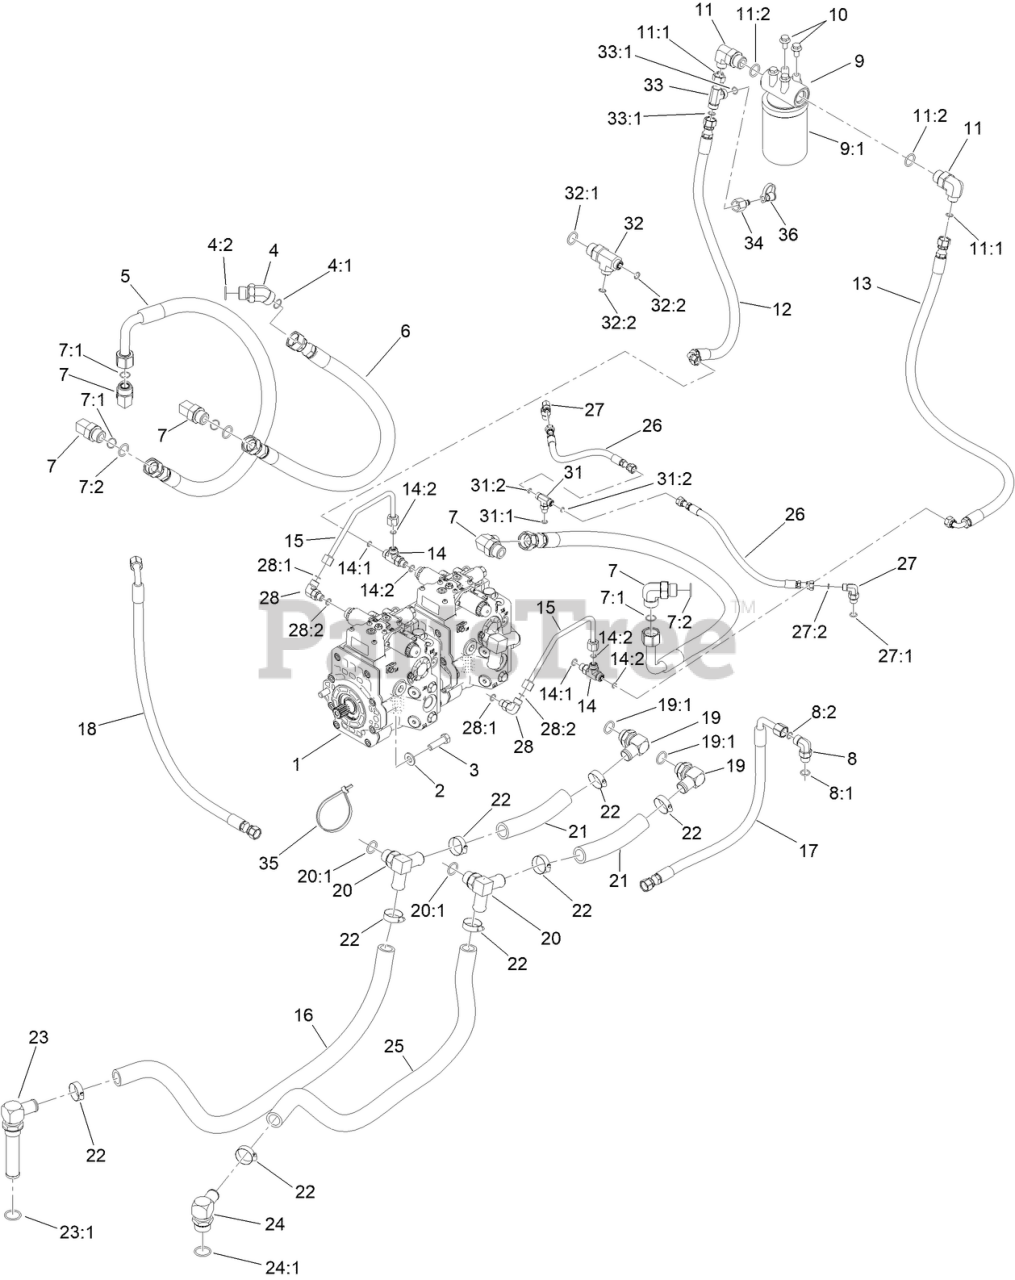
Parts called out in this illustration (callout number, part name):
1	HYD PUMP ASM
2	WASHER-THRUST
3	SCREW-HH
4	FITTING-45 DEG
4:1	O-RING
4:2	O-RING
5	HYD HOSE ASM
6	HYD HOSE ASM
7	FITTING-ELBOW-90
7:1	O-RING
7:2	O-RING
8	FITTING-ELBOW, 90 DEG
8:1	O-RING
8:2	O-RING
9	FILTER-OIL
9:1	FILTER-HYD
10	SCREW-HHF
11	FITTING-HYD, 90 DEG
11:1	O-RING
11:2	O-RING
12	HYD HOSE ASM
13	HYD HOSE ASM
14	FITTING-TEE
14:1	O-RING
14:2	O-RING
15	HYD TUBE ASM
17	HYD HOSE ASM
18	HYD HOSE ASM
19	FITTING-90
19:1	O-RING
20	CONNECTOR
20:1	O-RING
22	CLAMP-HOSE
23	STRAINER FITTING ASM
23:1	O-RING
24	STEM-BARB-90
24:1	O-RING
26	HYD HOSE ASM
27	FITTING-ELBOW, 90 DEG
27:1	O-RING
27:2	O-RING
28	FITTING-ELBOW, 90 DEG
28:1	O-RING
28:2	O-RING
31	FITTING-TEE
31:1	O-RING
31:2	O-RING
32	FITTING-TEE
32:1	O-RING
32:2	O-RING
33	FITTING-HYD, TEE
33:1	O-RING
34	FITTING
35	TIE-CABLE
36	CAP-DUST
